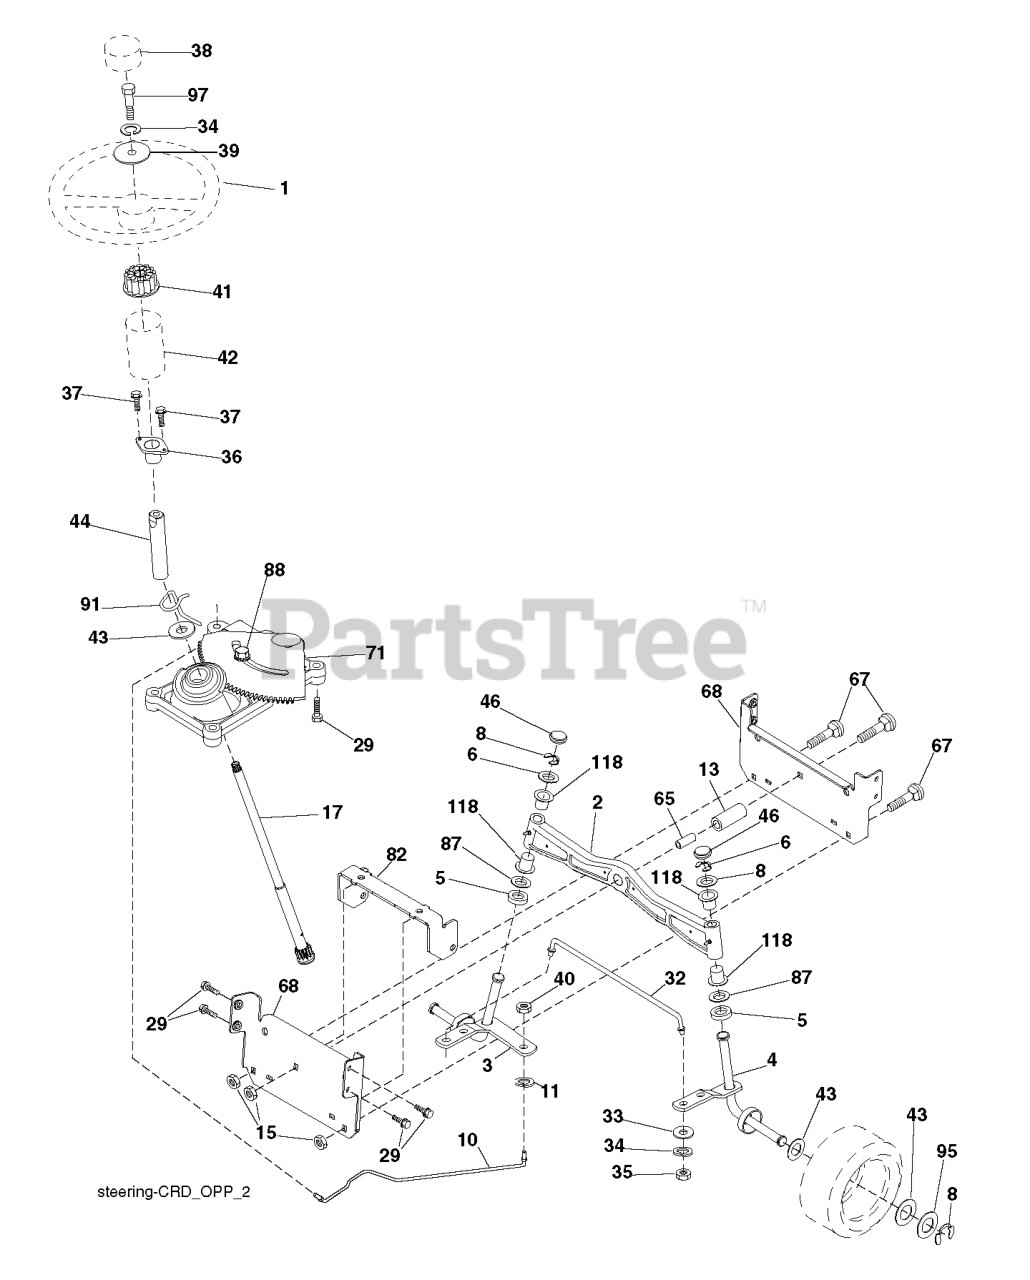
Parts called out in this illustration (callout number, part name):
1	RP WHEEL.STEER.HUSQ.PREM.OVMLD
2	AXLE.ASM.LT.CAST.LGHTWGHT
3	SPINDLE.ASM.LH.15"TIRES
4	SPINDLE.ASM.RH.15"TIRES
5	THRUST WASHER
10	DRAGLINK.15".TIRES.2001
11	WASHER, LOCK 3/8
13	TUBE, PIVOT AXLE
15	NUT
17	SHAFT STEERING SPLINE
29	SCREW, 3/8-16X3/4
33	WASHER M
34	WASHER.LOCK.HVY.HLCL.SPR.5/16
35	NUT, CROWNLOCK
36	BUSHING, STEERING
37	SCREW.TT.#10-32X.5.3/8.FLANGE
38	RP INSERT.CAP.WHL.STRG.HUSQ.
39	WASHER.11/32
40	NUT CROWNLOCK 3/8-24
41	ADAPTER, WHEEL STNG..
42	BOOT, STEERING
44	SHAFT.EXTEN.STRG.SPLINE
46	CAP.SPINDLE.BLACK
65	SPACER.BRACE.AXLE
67	BOLT CARRIAGE
68	BRACE.AXLE.15"TIRES
71	STEERING ASM
82	BRACKET.SUSP.CHASSIS.FRONT.15
87	WASHER, FLAT .781 X 1 1/2"
88	BOLT, SHOULDER 7/16-20
91	CLIP.STEERING
95	WASHER.HARDENED
97	BOLT 5/16-18 X 4 W/PATCH
118	BUSHING, AXLE CAST
